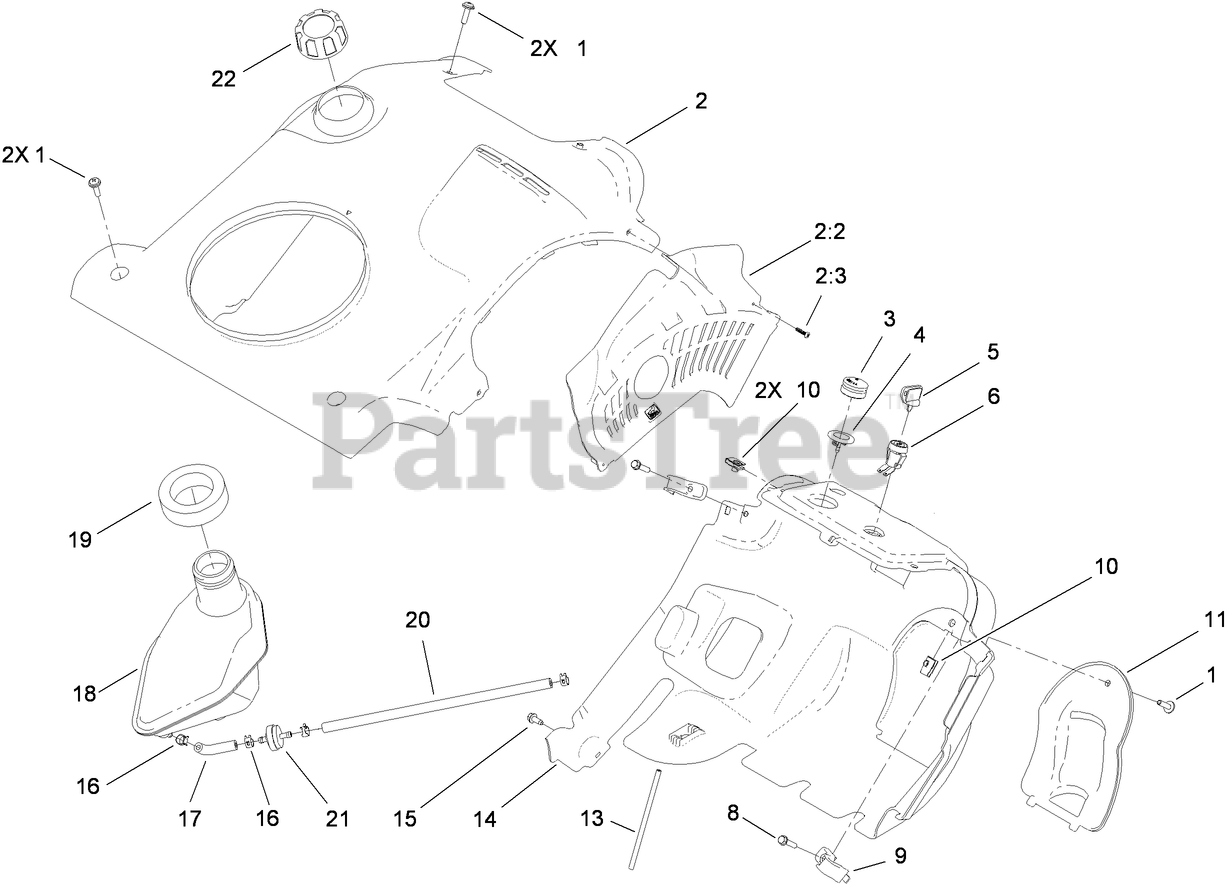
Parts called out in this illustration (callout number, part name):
1	SCREW-PPH
2	SHROUD ASM
2:2	BAFFLE-HEAT
2:3	SCREW-PPH
3	BULB-PRIMER
4	BODY-PRIMER
5	KEY-IGNITION
6	SWITCH
8	SCREW-PLASTITE
9	CLIP-SHROUD
11	PANEL-ACCESS, CARBURETOR
13	HOSE-PRIMER
14	SHROUD-LOWER
15	SCREW-HWH
16	CLAMP-HOSE
17	HOSE-FUEL
19	SEAL-TANK
20	HOSE-FUEL
21	FILTER-FUEL
22	GAS CAP ASM
